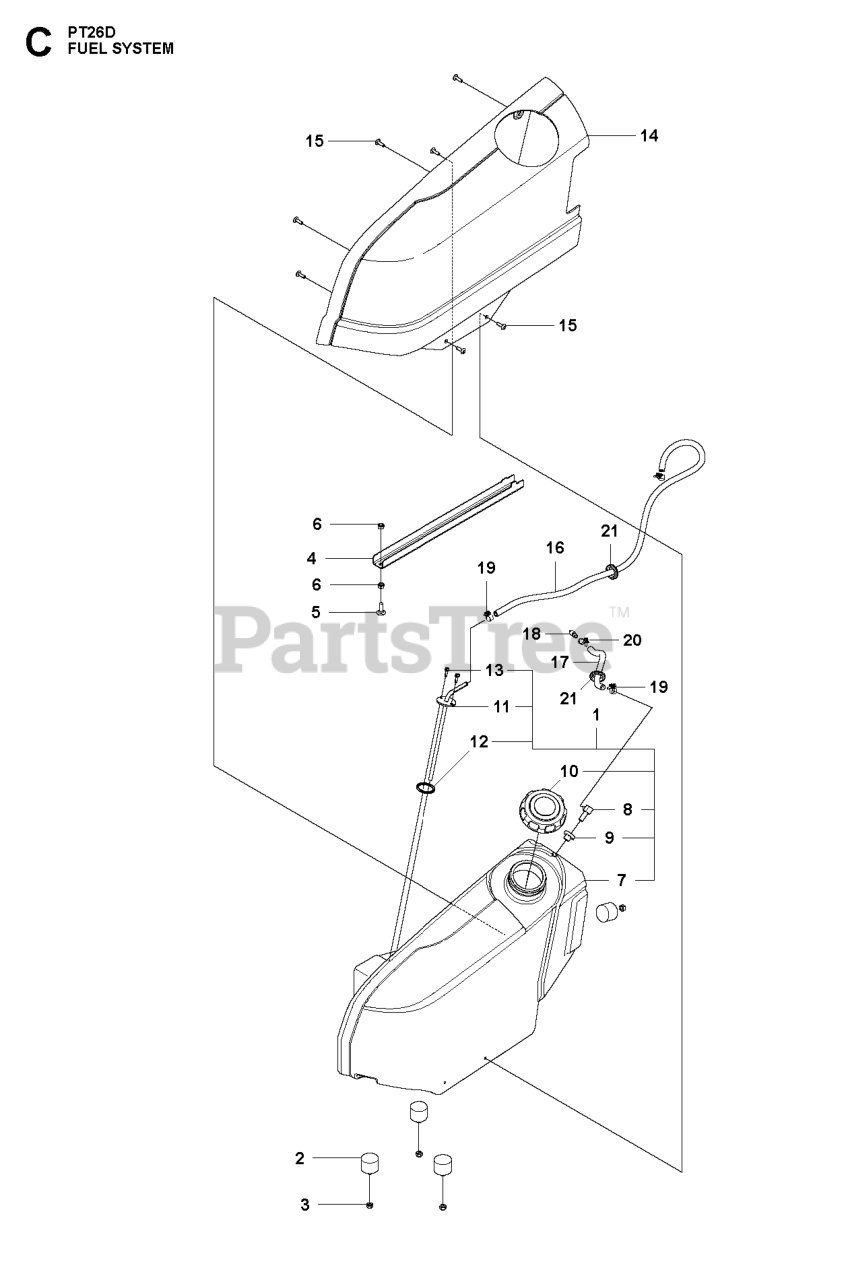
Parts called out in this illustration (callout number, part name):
2	ANTIVIBRATION ELEMENT
3	LOCKNUT M8
6	LOCKNUT M8
9	RUBBER GROMMET
10	TANK CAP - DIESEL
11	CONNECTION FUEL TANK
19	RP HOSE CLAMP FUEL HOSE
20	HOSE CLAMP FUEL HOSE
